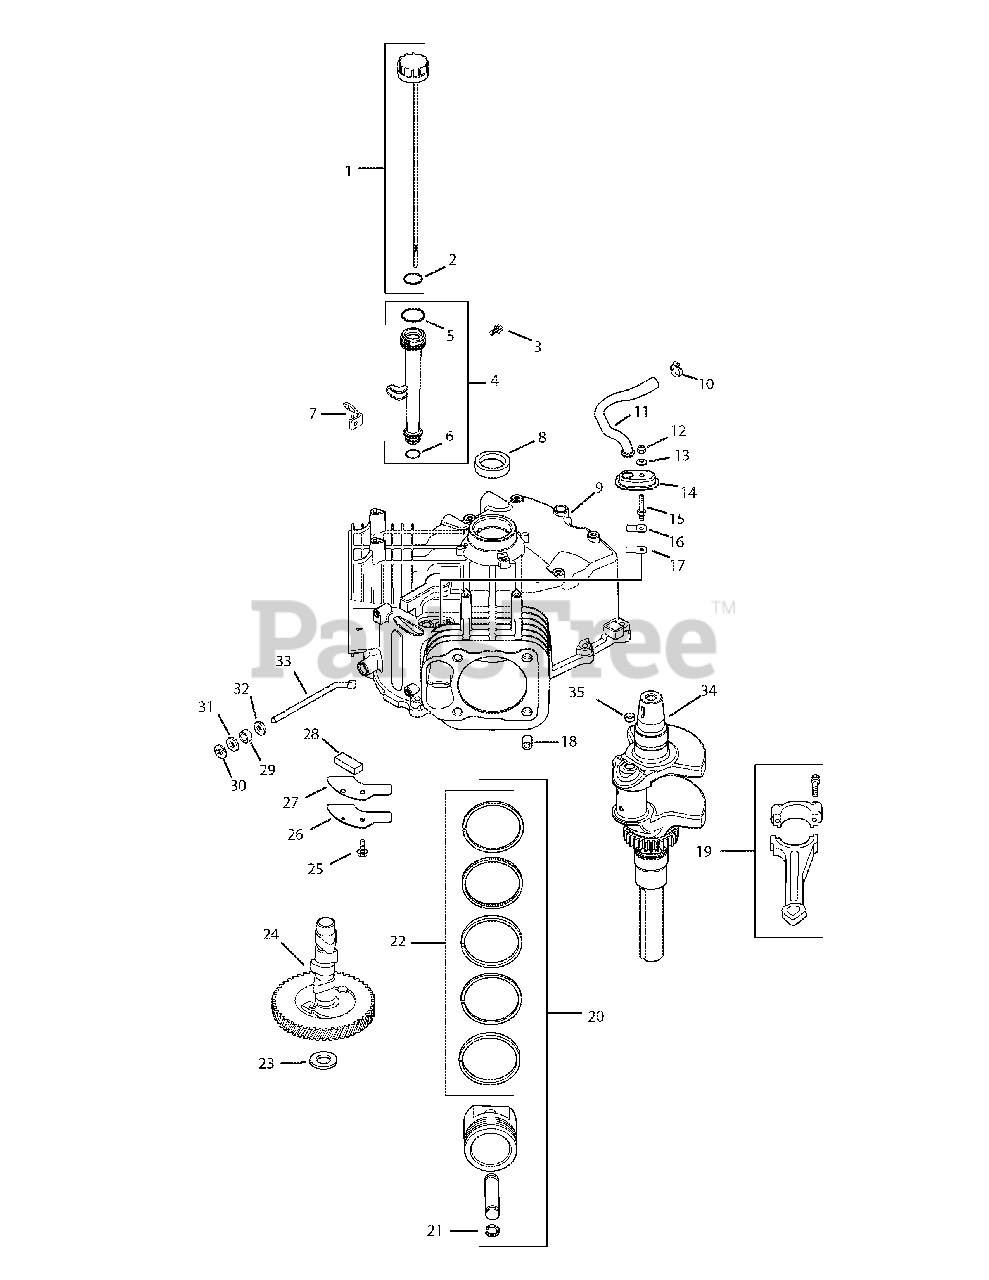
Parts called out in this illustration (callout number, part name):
1	Kit, dipstick
3	Screw, hex. flange M5x0.8x16
4	Tube, oil fill
5	O-Ring, upper oil fill tube
6	O-Ring, lower oil fill tube
7	Bracket, oil fill tube
8	Seal, oil
9	Crankcase (Use: Miniblock )
10	Clamp, hose
11	Hose, breather
12	Nut, hex. lock M5x0.8
13	Washer, sealing
14	Housing, breather
15	Stud, breather cover
16	Retainer, breather reed
17	Reed, breather
18	Pin, locating
19	Connecting Rod (Std.)
20	Piston w/Ring Set (Std.)
20	Piston w/Ring Set (.08)
20	Piston w/Ring Set (.25)
21	Retainer, piston pin
22	Ring Set (Std.)
22	Ring Set (.25)
23	Shim, camshaft (yellow)
23	Shim, camshaft (red)
23	Shim, camshaft (black)
23	Shim, camshaft (white)
23	Shim, camshaft (blue)
23	Shim, camshaft (green)
23	Shim, camshaft (gray)
24	Kit, camshaft
25	Screw, hex. flange M6x1.0x16
26	Cover, breather
27	Gasket, breather cover
28	Filter, breather
29	Seal, governor cross shaft
30	Ring, retainer
31	Washer, plain 8 mm
32	Washer, flat 1/4"
33	Shaft, governor cross
34	Crankshaft
